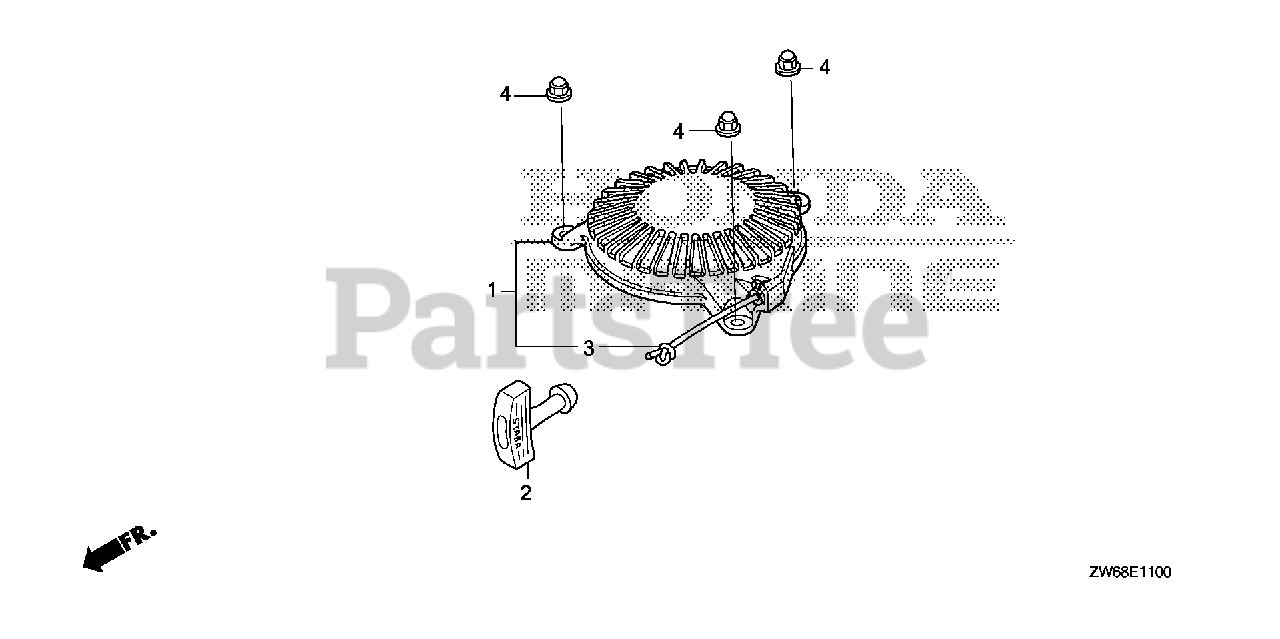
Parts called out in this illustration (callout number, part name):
1	STARTER ASSY., RECOIL
2	KNOB, STARTER
3	ROPE, RECOIL STARTER
4	NUT, FLANGE CAP (5MM)
